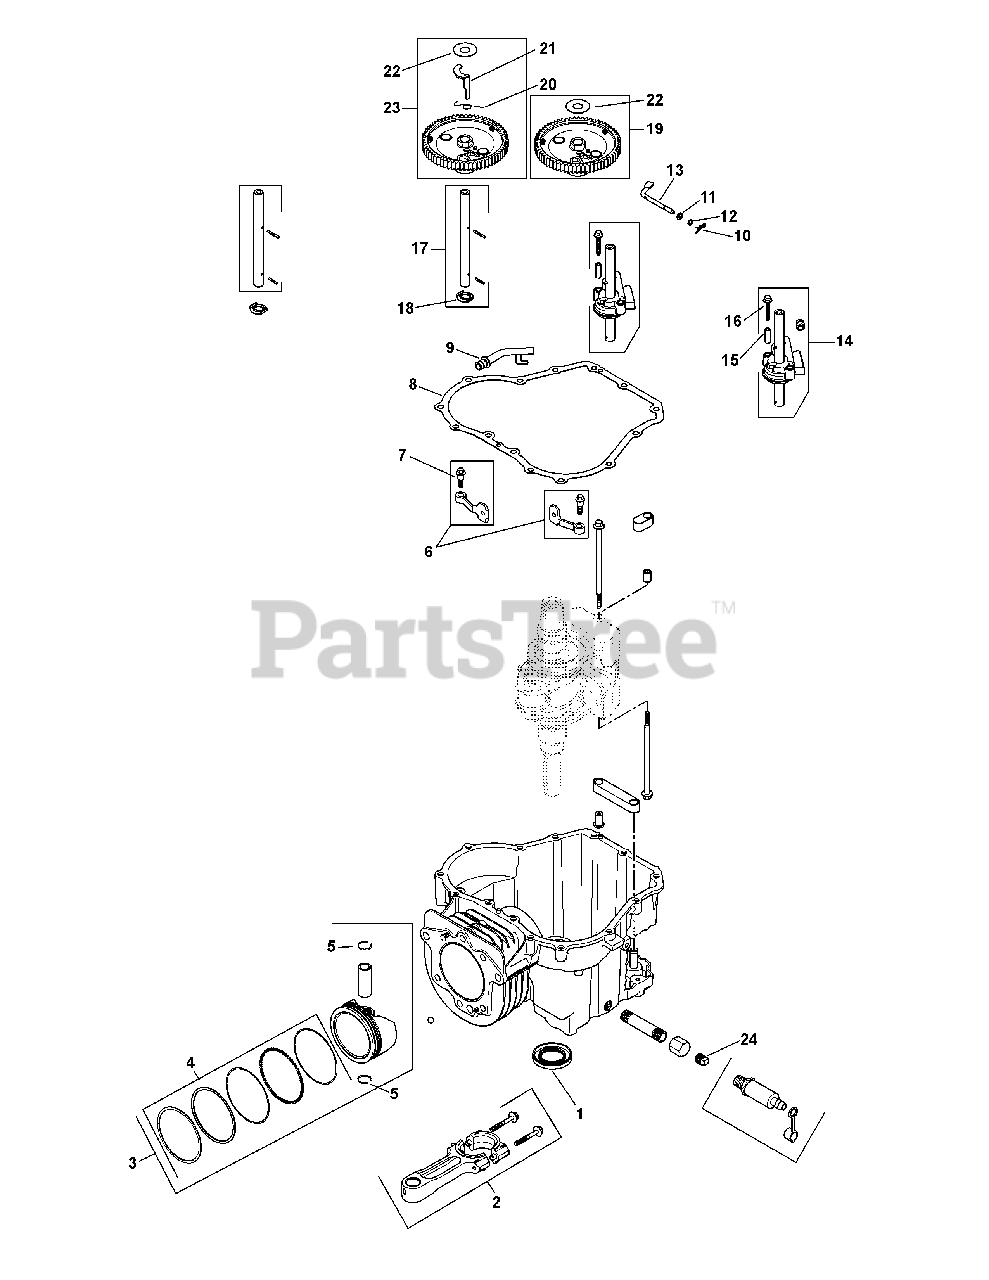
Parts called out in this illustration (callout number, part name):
1	Oil Seal
2	Connecting Assembly Rod
3	Piston w/ Ring Set Kit, 94mm (Inc. 4 & 5)
4	Ring Set, 94mm
5	Piston Pin Retainer
6	Cam Lever Assembly Kit (Inc. 7)
7	Shd. Thd. Frm. Screw M6 x 1 x 26
8	Closure Plate Gasket
9	Drainback Tube
10	Hitch Pin Clip
11	Flat Washer, 6 mm
12	Flat Washer, 1.4
13	Governor Cross Shaft
14	Oil Pump Assembly Kit (Inc. 8, 15 & 16)
15	Oil Pump Screw Spacer
16	Oil Pump Screw
17	Cam Center Shaft Kit, Exhaust (Inc. 18)
18	Thrust Washer
19	Camshaft Assembly Kit (Inc. 20-22)
21	ACR Weight
22	Thrust-ACR Washer
23	Camshaft Assembly Kit (Inc. 22)
24	Sq. Hd. Pipe Plug, 3.8
